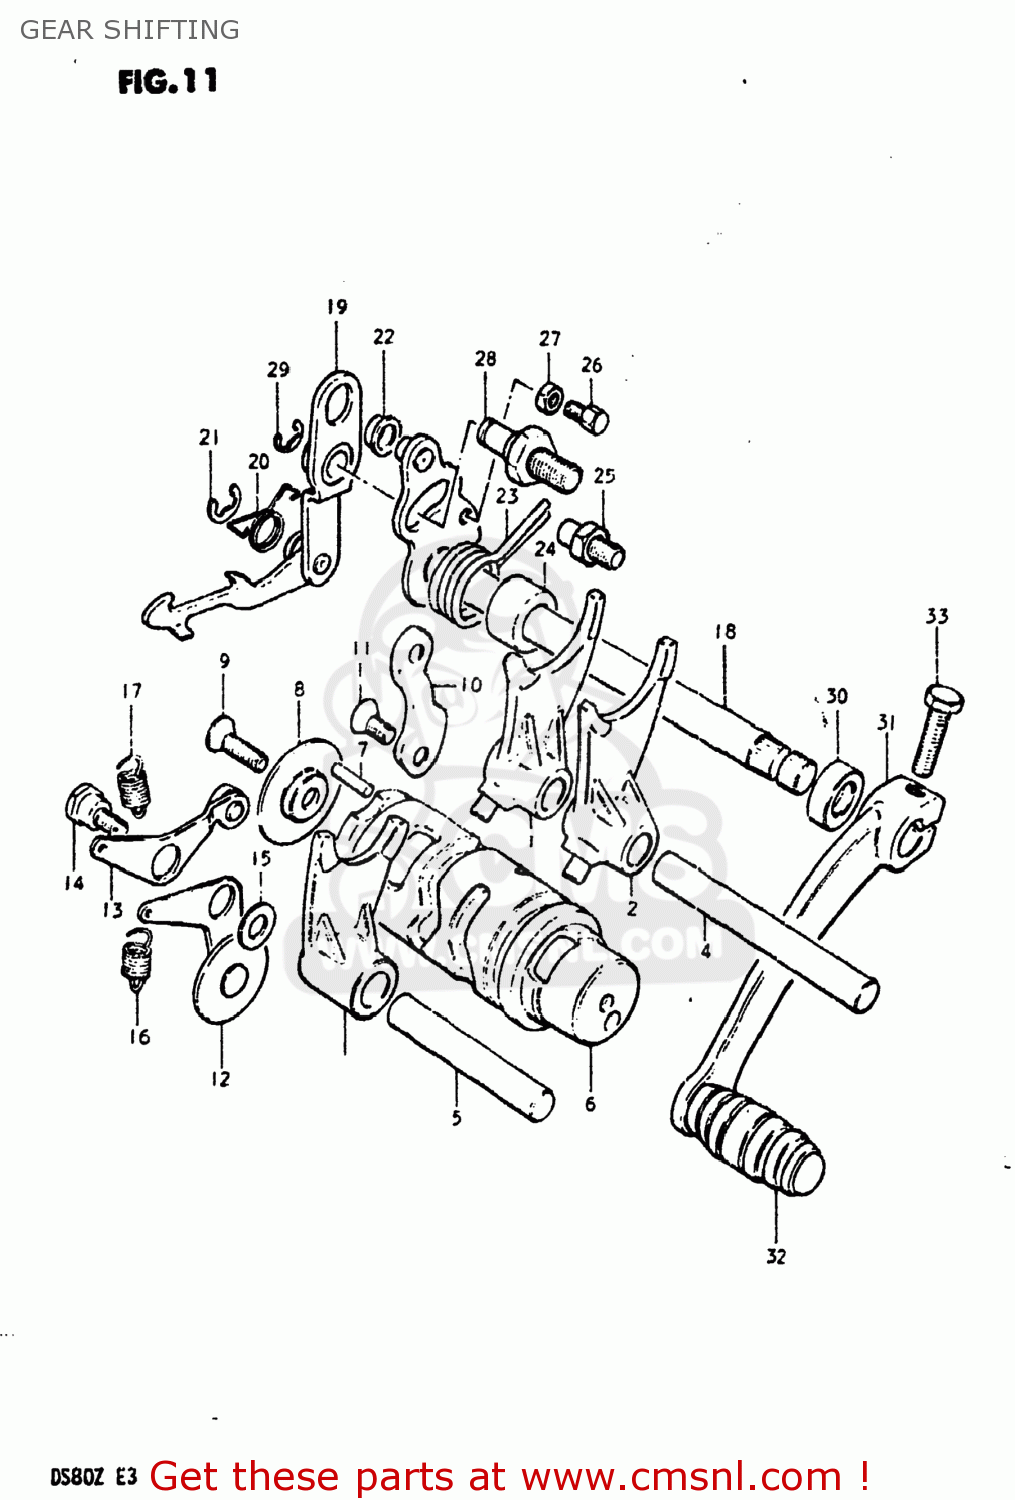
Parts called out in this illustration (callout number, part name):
1	FORK,GEAR SHIFT NO.1
2	FORK,GEAR SHIFT NO.2
3	FORK,GEAR SHIFT NO.2
4	SHAFT,GEAR SHIFT FORK
5	SHAFT,GEAR SHIFT FORK
6	CAM,GEAR SHIFT
7	PIN
8	RETAINER,GEAR SHIFT CAM DR PIN
9	SCREW
10	GUIDE,GEAR SHIFT CAM
11	SCREW
12	STOPPER,GEAR SHIFT CAM
13	STOPPER,GEAR SHIFT CAM NEUTRAL
14	BOLT(6X18.3)
15	WASHER
16	SPRING
17	SPRING
18	SHAFT,GEAR SHIFT
19	PAWL,GEAR SHIFT
20	SPRING
21	E RING
22	SPACER(7X10X5)
23	SPRING
24	SPACER(12X20X15.3)
25	STOPPER,GEAR SHIFT CAM
26	BOLT,GEAR SHAFT RETURN SPR SET
27	NUT 6MM
28	STOPPER,GEAR SHIFT CAM
29	E RING 6MM
30	OIL SEAL
31	LEVER ASSEMBLY,GEAR SHIFTING
32	RUBBER,GEAR SHIFT PEDAL
33	BOLT
